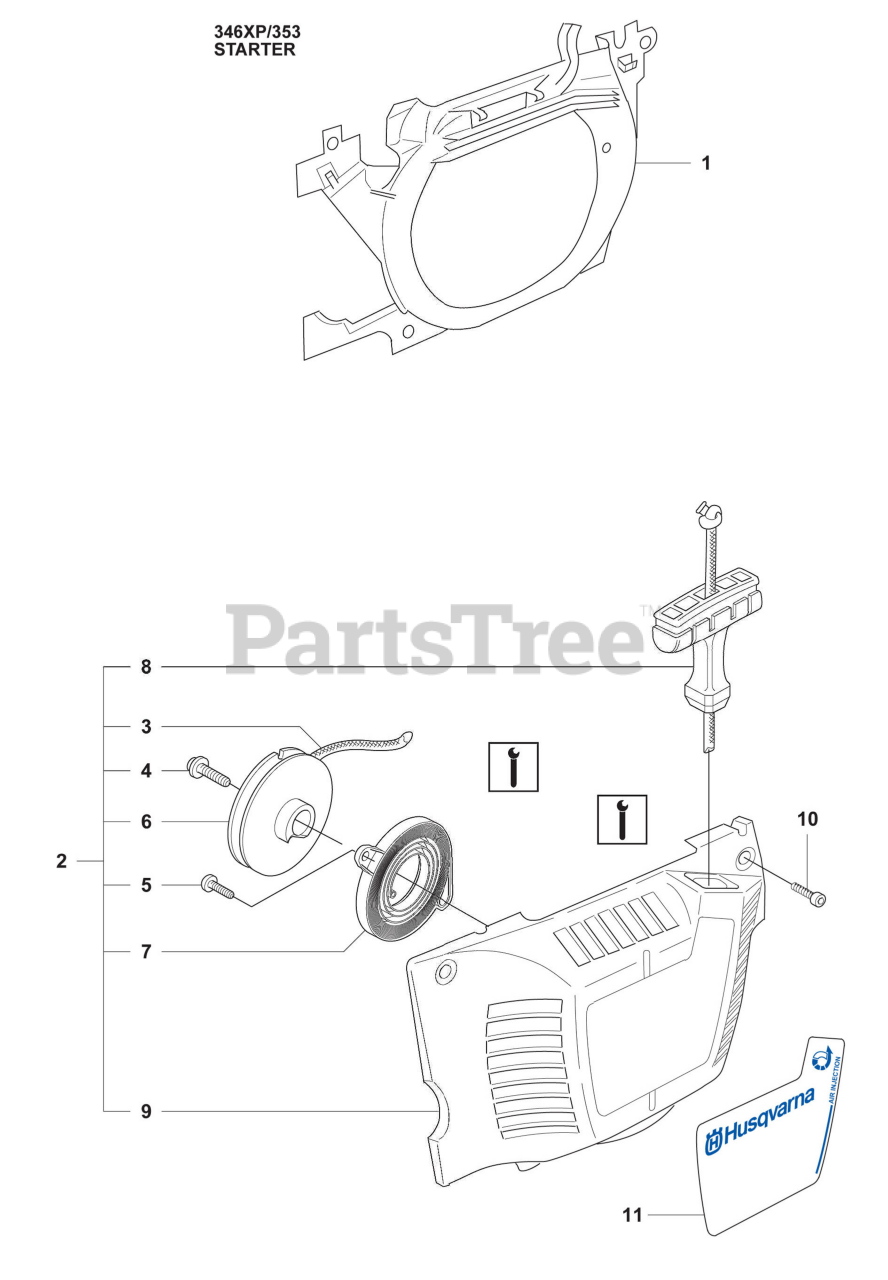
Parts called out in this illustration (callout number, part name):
1	Air Conductor
2	Starter Housing Assembly, Red
3	Starter Rope
6	Starter Pulley
7	Return Spring
8	Starter Handle
9	Starter Housing
10	Screw, Citxpanmo
11	Decal
11	DECAL
